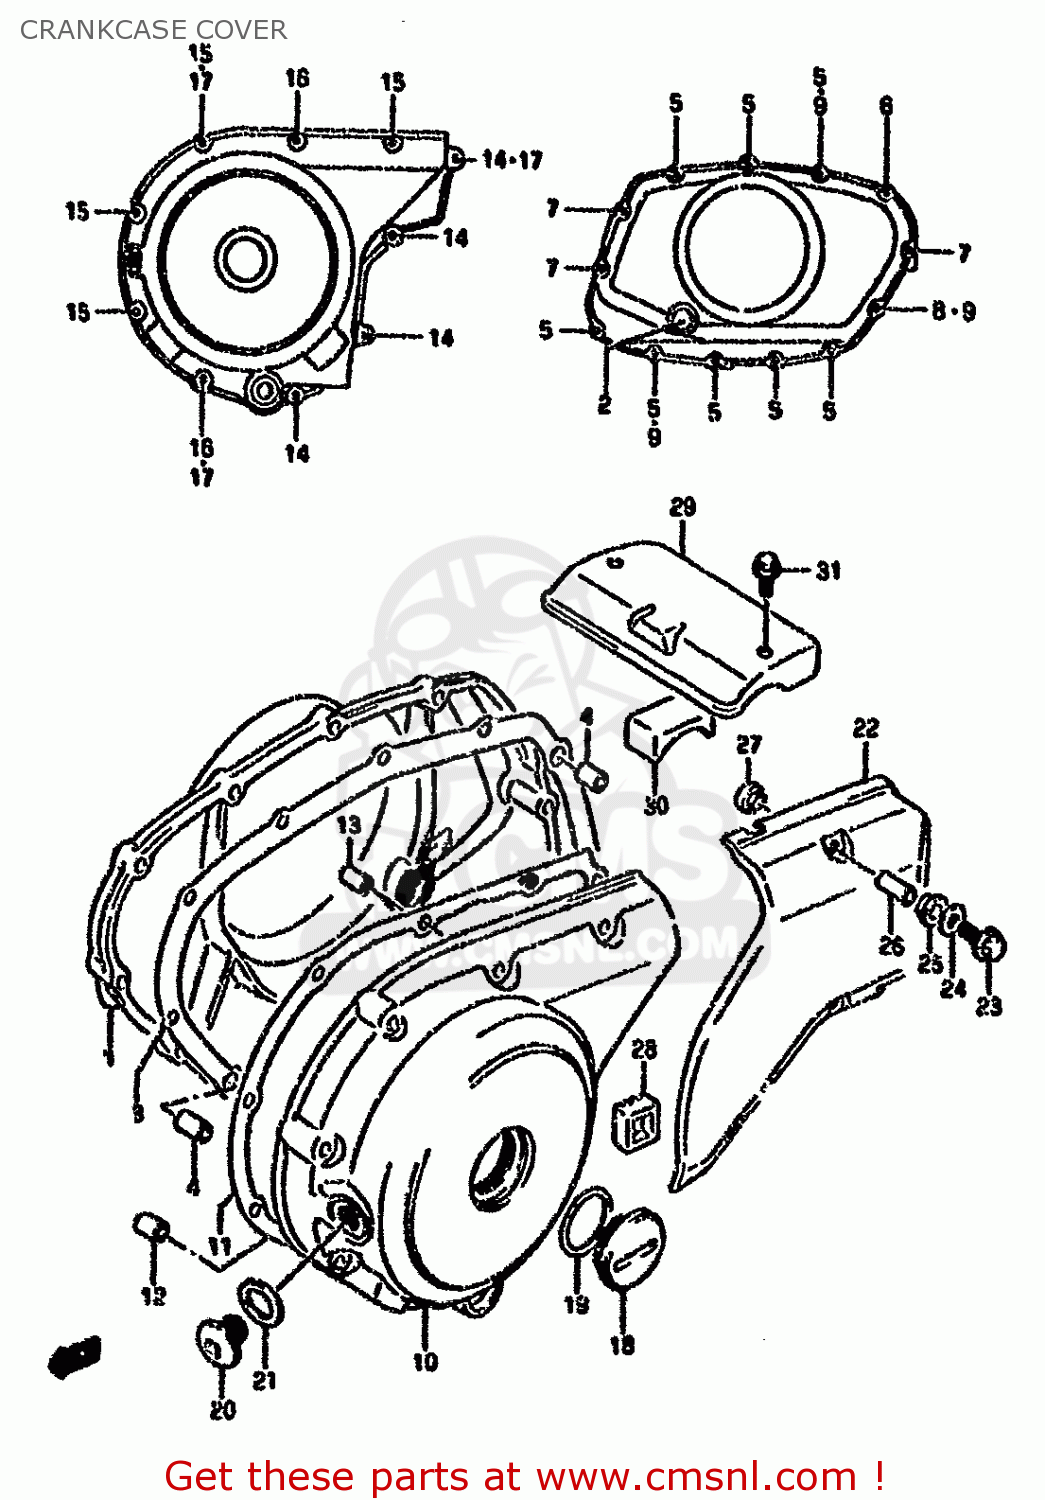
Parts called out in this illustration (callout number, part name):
1	COVER,CLUTCH
2	LENS,OIL LEVEL CHECK
3	GASKET,CLUTCH COVER (NAS)
4	PIN
5	BOLT
6	BOLT
7	BOLT
8	BOLT
9	GASKET(5.8X13X1.2) (NAS)
10	COVER,GENERATO
11	GASKET,GENERATOR COVER (NAS)
12	PIN (11X20)(SUS)
13	PIN
14	BOLT
15	BOLT
16	BOLT
17	GASKET(5.8X13X1.2) (NAS)
18	PLUG
19	O RING(D:3.1,ID:32.7)
20	PLUG,14X12
21	GASKET(13.8X18.8X4.8) (NAS)
22	COVER,SECONDARY GEAR CASE
23	BOLT
24	WASHER
25	WASHER(8.7X15X2.1)
26	SPACER
27	WASHER(8.7X16X5)
28	DAMPER,SECONDARY COVER
29	COVER,STARTER MOTOR
30	DAMPER,MOTOR COVER
31	BOLT
